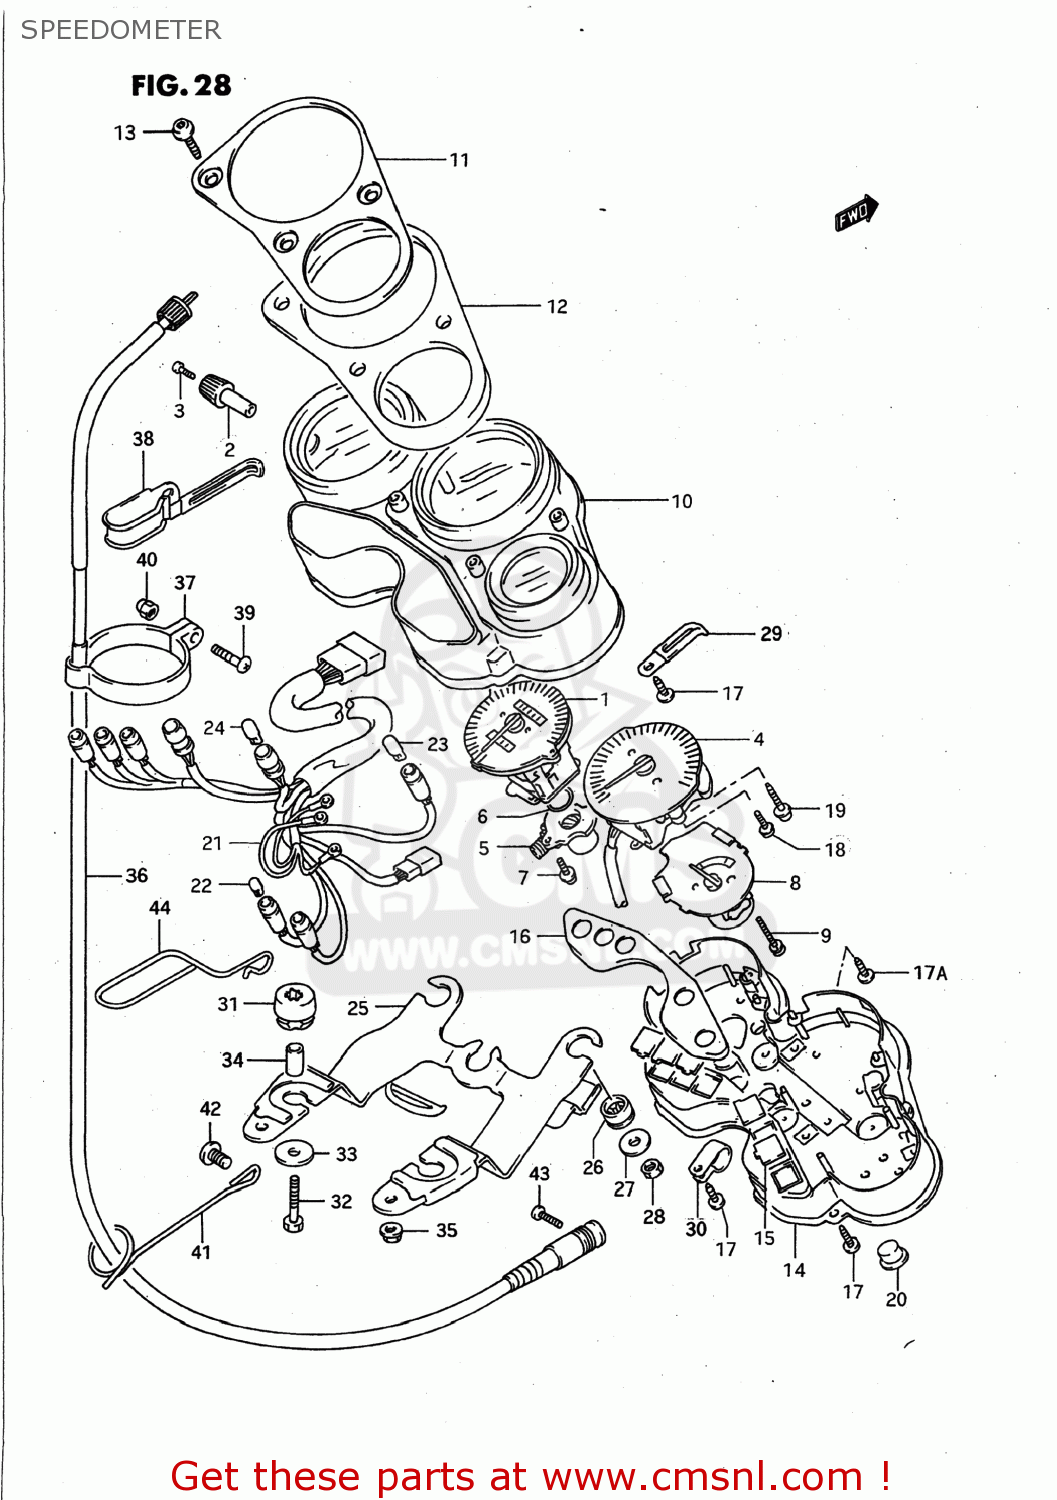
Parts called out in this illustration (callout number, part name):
1	SPEEDOMETER
2	KNOB,TRIP
3	SCREW(2X6)
4	TACHOMETER
5	BOX,METER GEAR
6	O RING
7	SCREW
8	METER,TEMPERATURE
9	SCREW(3X22)
10	HOOD
11	PANEL,METER
12	CUSHION
13	SCREW
14	CASE,METER
15	LENS SET
16	PANEL
17	SCREW(4X14)
17A	SCREW
18	SCREW
19	SCREW(4X22)
20	CAP
21	SOCKET
22	BULB(12V3W,T6.5)
23	BULB(12V1.7W,T6.5)
24	BULB(12V1.7W,T10,WB121)
25	BRACKET,METER
26	CUSHION
27	SPACER,METER
28	NUT
29	CLAMP
30	CLAMP
31	GROMMET
32	BOLT
33	WASHER (6.5X20X1.6)
34	SPACER
35	NUT
36	CABLE ASSY,SPEEDOMETER
37	GUIDE,SPEEDOMETER CABLE
38	GUIDE,METER CABLE NO.1
39	SCREW
40	NUT
41	GUIDE,SPEEDOMETER CABLE,R
42	SCREW
43	SCREW
44	GUIDE,METER CABLE NO.2
